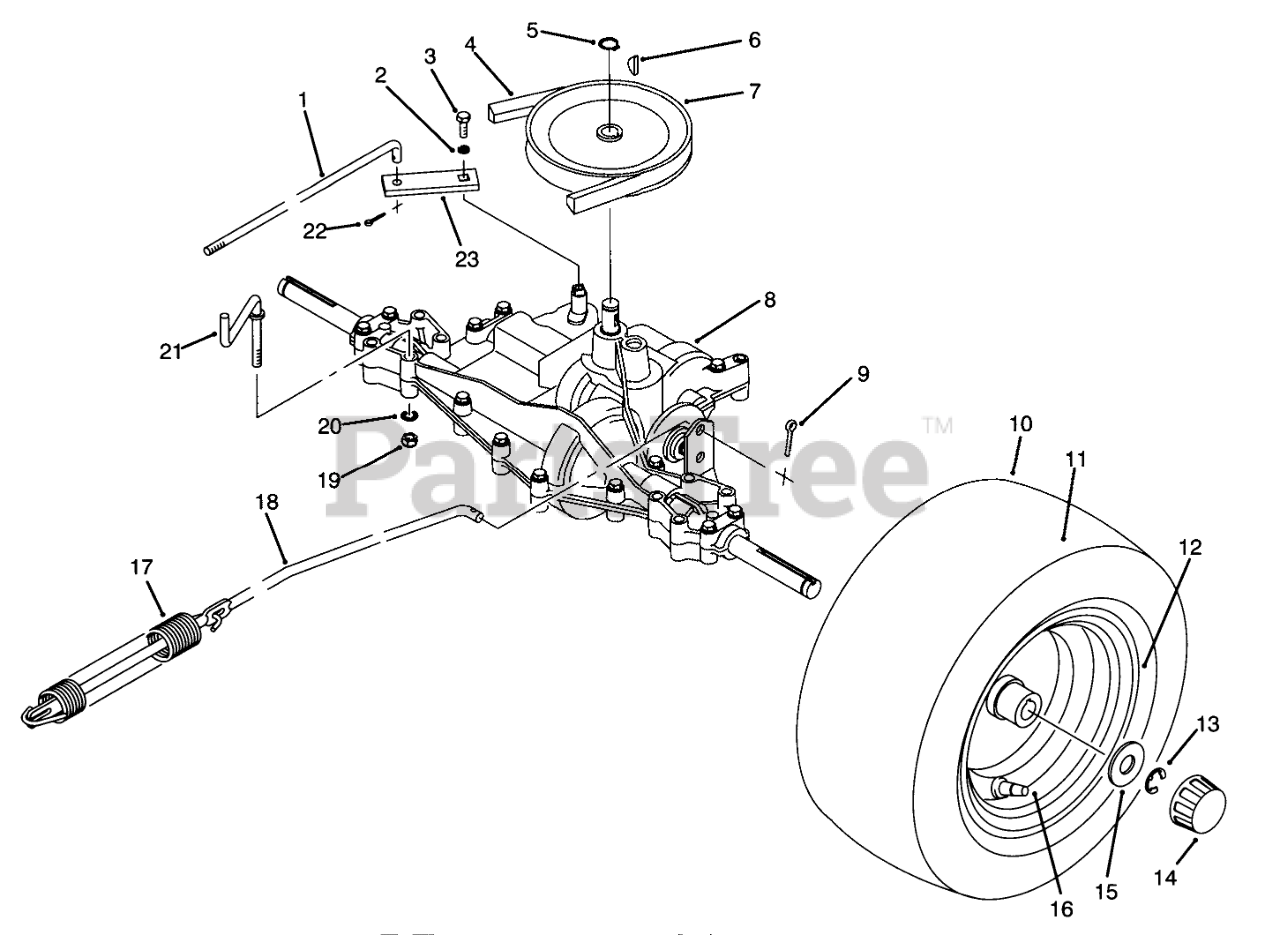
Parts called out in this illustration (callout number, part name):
1	LINK-SHIFT
2	WASHER-LOCK
3	SCREW-HH
4	V-BELT, TRACTION
5	RING-SNAP, EXTERNAL
6	KEY-WOODRUFF
7	PULLEY-TRANSAXLE
8	TRANSAXLE 915-019
9	PIN-COTTER
11	TUBE-INNER
12	REAR WHEEL ASM
13	E-RING
14	CAP-HUB
15	WASHER-PLAIN
16	STEM-VALVE
17	SPRING-EXT
18	ROD-BRAKE
19	NUT-LOCK, NI
20	WASHER-LOCK, INTERNAL
21	GUIDE-LOWER BELT
22	PIN-COTTER
23	LINKAGE
